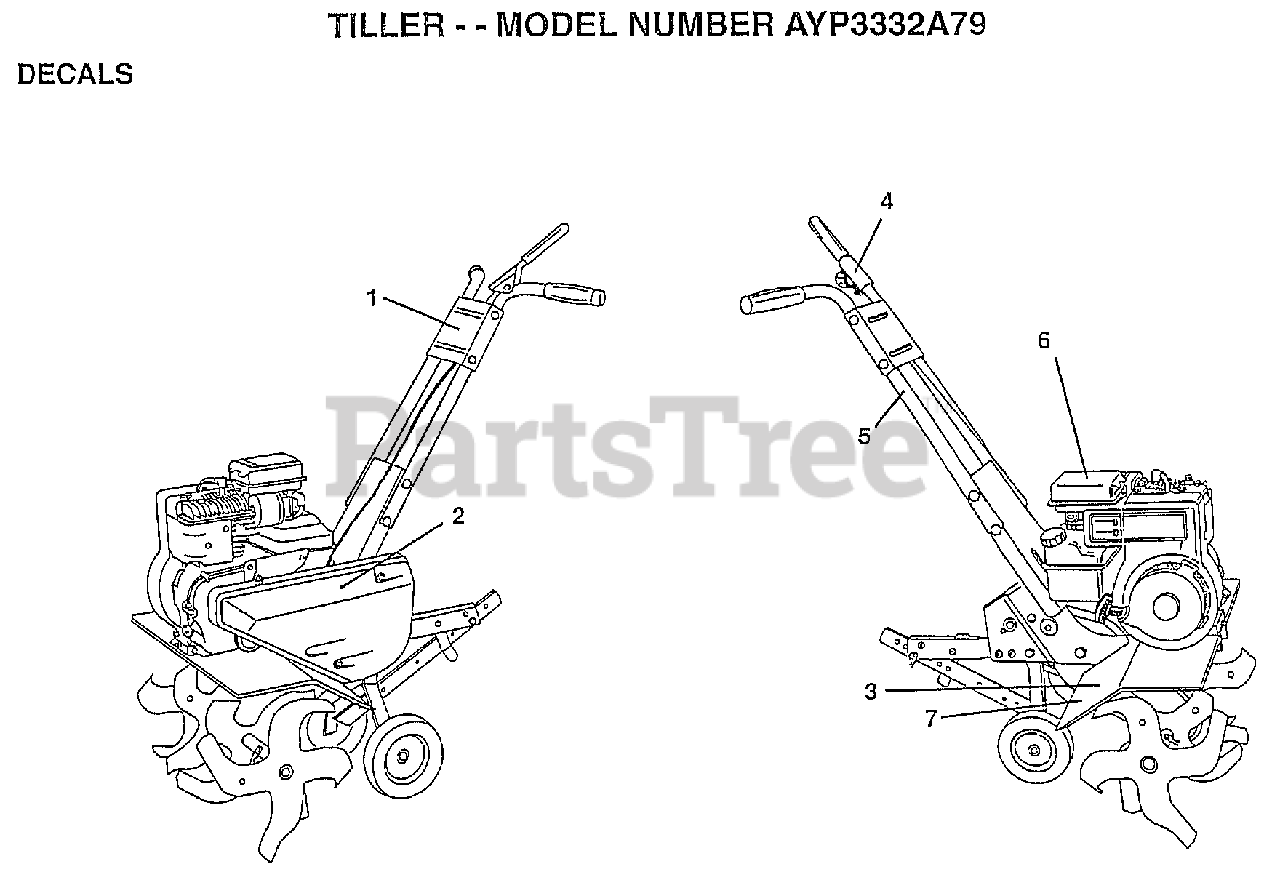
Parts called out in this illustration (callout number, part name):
1	DECAL PANEL CONT
2	DECAL.LOGO
4	DECAL TI
5	DECAL TI
7	DECAL TI
